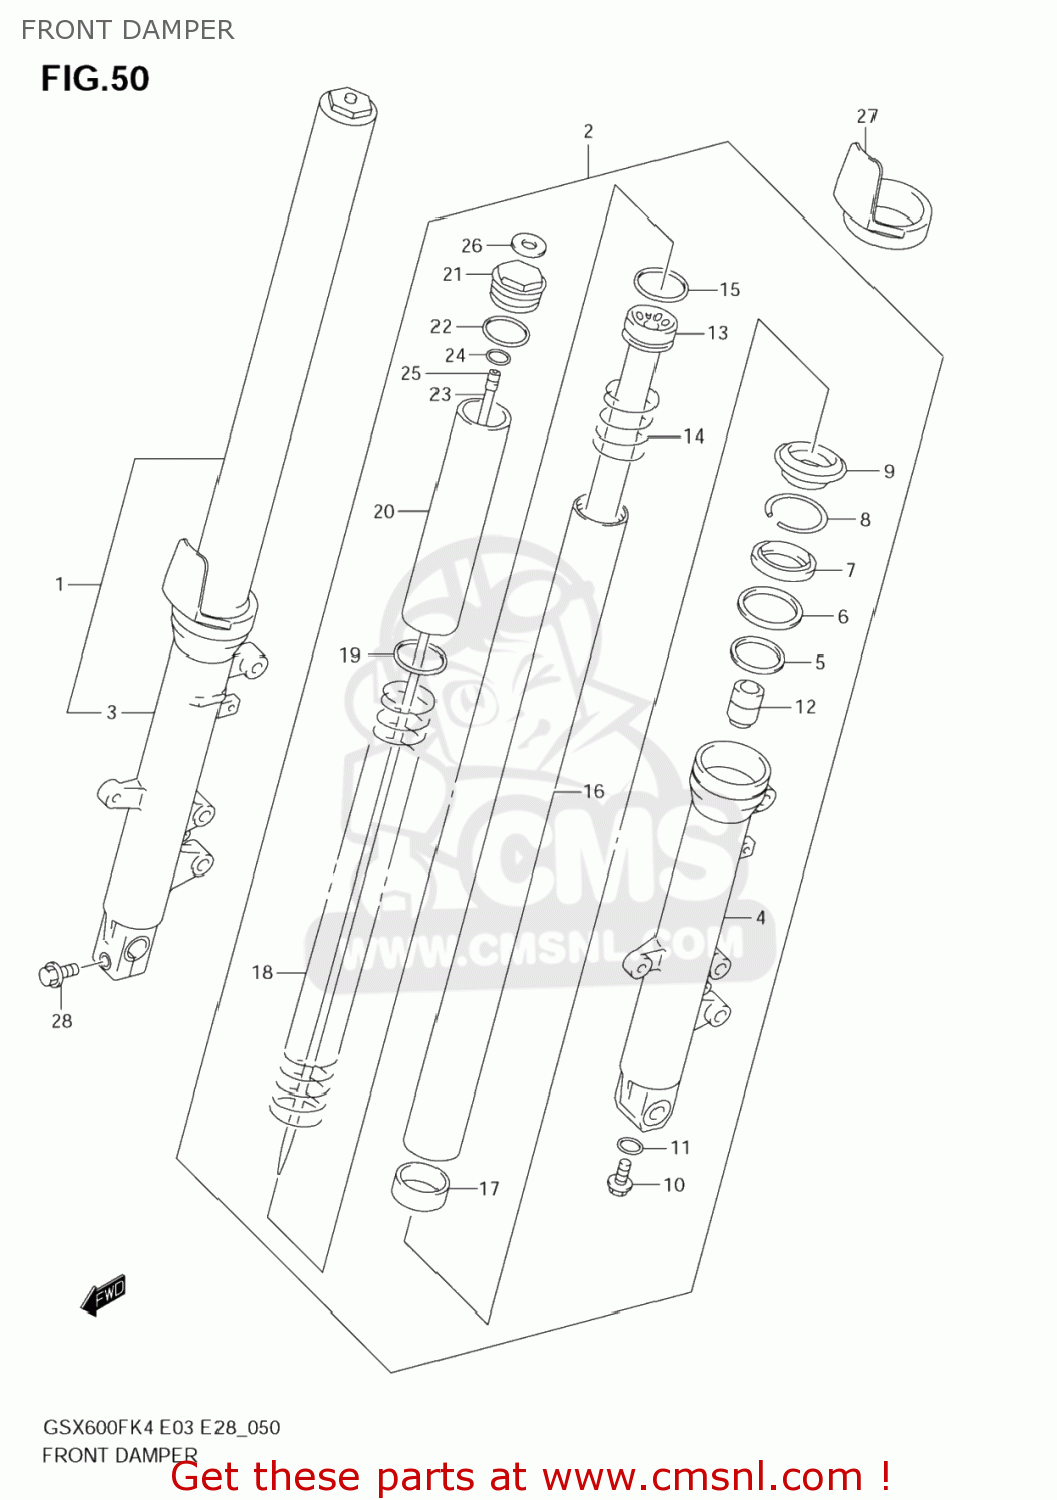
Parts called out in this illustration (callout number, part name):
1	DAMPER ASSY,FR FORK,R
2	DAMPER ASSY,FR FORK,L
3	TUBE,OUTER,R
4	TUBE,OUTER,L
5	BUSH,GUIDE
6	SPACER,SEAL
7	SEAL,OIL
8	CIRCLIP,FORK OIL SEAL
9	SEAL,DUST
10	BOLT(8X27)
11	GASKET (NAS)
12	PIECE,OIL LOCK
13	SEAT,UNDER
14	SPRING,REBOUND
15	RING,PISTON
16	TUBE,INNER
17	BUSH,SLIDE
18	SPRING,FR
19	JOINT,SPRING
20	SPACER,SPRING
21	BOLT,FORK
22	O RING
23	ROD,DAMPER
24	O RING(D:1.9,ID:3.8)
25	RING,STOPPER(ID:6.1,D:0.6)
26	LABEL,S-H
27	PROTECTOR
28	BOLT
